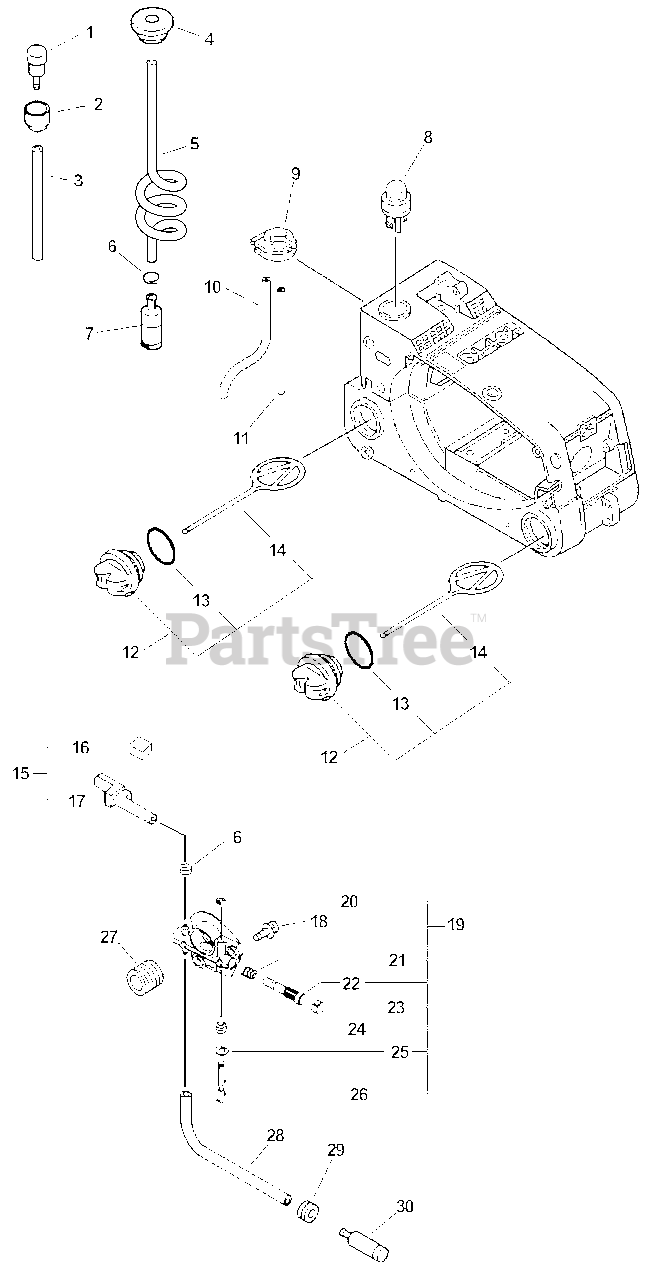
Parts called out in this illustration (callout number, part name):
1	VENT, FUEL TANK
2	HOLDER, VENT
3	PIPE - 3X5X150 -- BLACK
4	GROMMET
5	PIPE, FUEL - SPIRAL
6	CLIP - 6.5
7	FILTER, FUEL
8	PUMP, PURGE
10	PIPE - 2X4X42 -- CLEAR
11	PIPE - 3X5X70 -- BLACK
12	CAP ASSY - ORANGE
13	O-RING - 25
14	CONNECTOR, CAP
15	OIL PIPE KIT
16	PAD, FOAM
17	PIPE - OIL
18	SCREW - 5X12
19	AUTO-OILER ASSY
20	RING, RETAINING
21	SPRING, PLUNGER
22	PLUNGER ASSY
23	CAP, OIL PUMP
26	NEEDLE, ADJUST
27	GEAR - WORM
28	PIPE - 3X6X115 -- BLACK
29	GROMMET
30	FILTER, OIL
